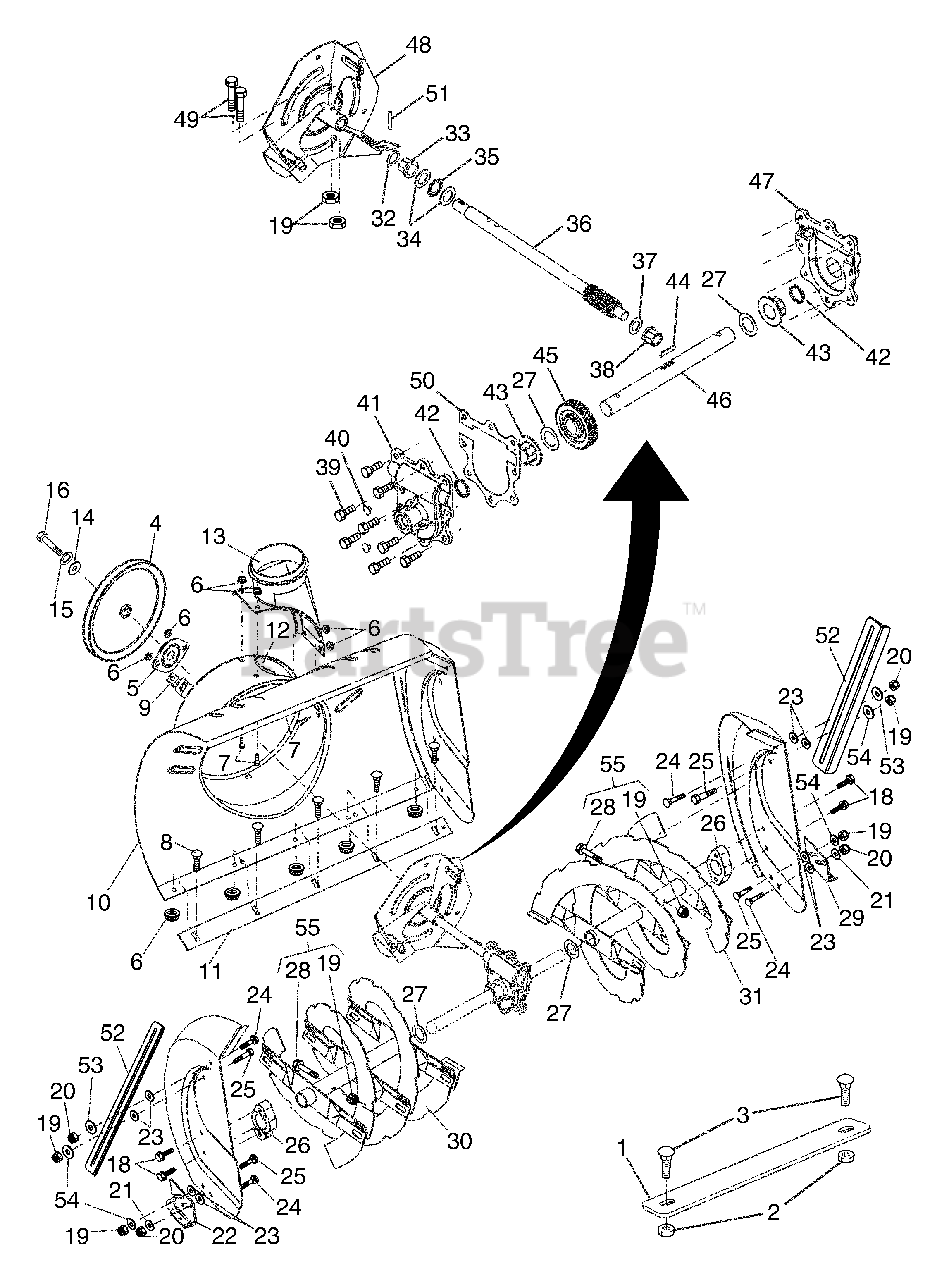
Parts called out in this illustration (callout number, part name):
2	Nut, Hex
3	Bolt, Carriage
4	Pulley, Impeller
5	Bearing Assembly, Flange
6	Nut, Hex Flange 5/16-18
7	Bolt, Flat Head, Carriage 5/16-18 x 5/8
8	Bolt, Carriage 5/16-18 x 5/8
9	Nut, Cage 3/8-16
10	Housing, Auger
11	Bar, Scraper
12	Bracket, Corner Discharge
13	Base, Discharge Chute
14	Washer, Flat
15	Washer, Lock 5/16
16	Screw, Hex Head 5/16-18 x 3/4
18	Screw, Hex Head 5/16 x 1
19	Nut, Hex Lock 1/4-20
20	Nut, Hex Lock 5/16-18
21	Washer, Flat
22	Skid Plate, RH
23	Washer, Nylon, Friction
24	Bolt, Carriage 5/16-18 x 3/4
25	Bolt, Shoulder
26	Bearing, Auger
27	Washer, Thrust, 1"
28	Bolt, Shear
29	Skid Plate, LH
30	Auger Assembly, RH
31	Auger Assembly, LH
32	O-Ring
33	Bushing, Flange 3/4
34	Washer, Thrust 3/4
35	Bearing, Thrust 3/4
36	Shaft, Impeller
37	Washer, Thrust 5/8
38	Bushing, Flange 5/8
39	Screw, Hex Head 5/16-18 x 3/4
40	Plug, Case
41	Housing, Gearbox, RH
43	Bushing, Flange, 1"
44	Key, Square 1/4 x 1/4 x 7/8
45	Gear, Worm
46	Shaft, Auger
47	Housing, Gearbox, LH
48	Impeller Assembly
49	Screw, Hex Head 1/4-20 x 1-5/8
50	Gasket, Gearbox
51	Pin, Roll 3/16 x 1-1/8
52	Bar, Drift Cutter
53	Washer, Flat
54	Washer, Flat 1/4
55	Kit, Shear
